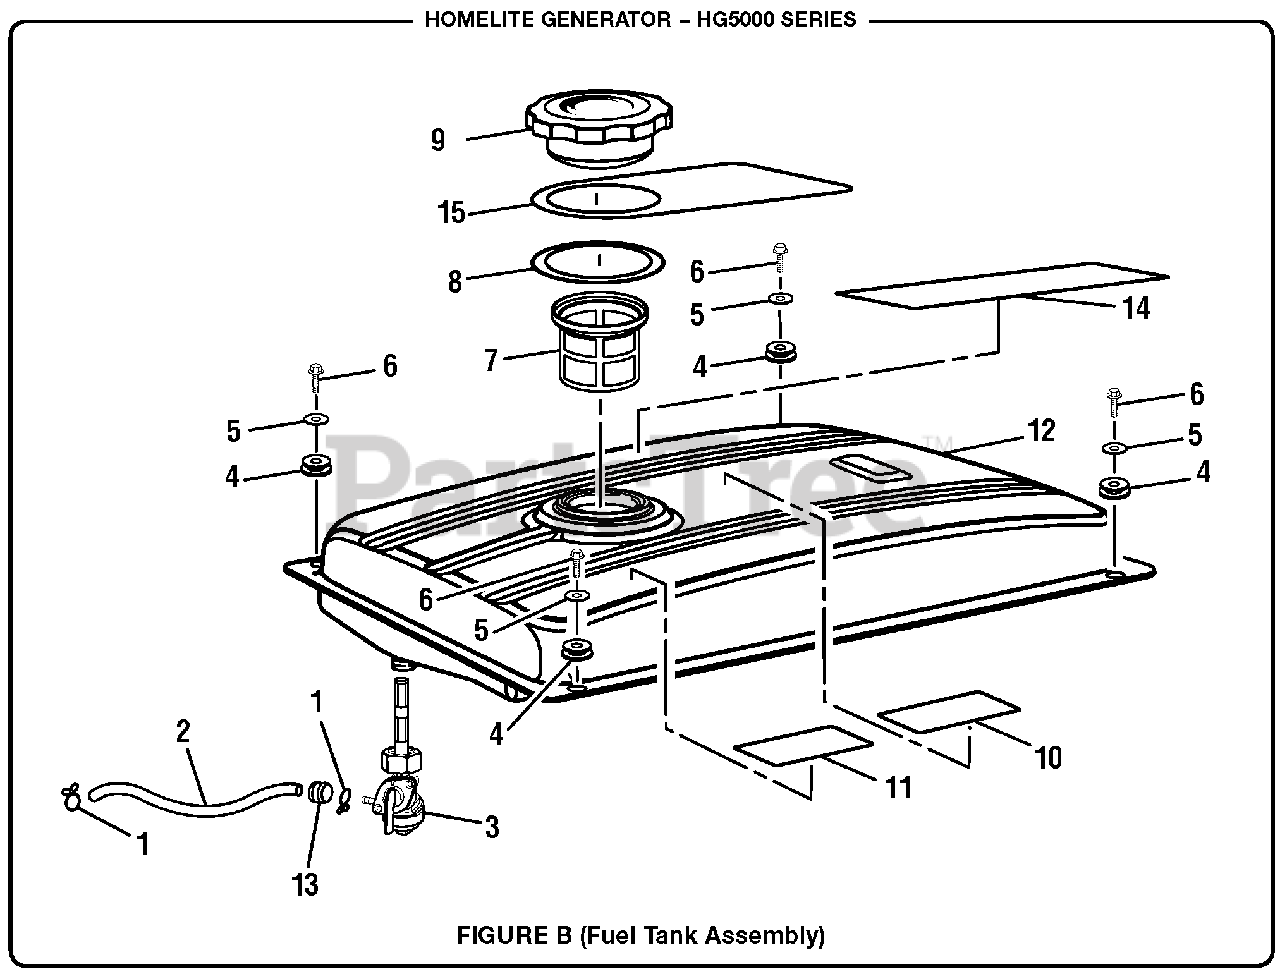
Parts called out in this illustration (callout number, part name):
1	Fuel Line Clamp
2	Fuel Line Hose
3	Fuel Valve Assembly
4	Bushing w/Insert
5	Washer (M6)
6	Bolt (M6 x 25 mm, Flange Hd.)
7	Fuel Tank Screen
8	Gasket (Fuel Cap)
9	Fuel Cap Assembly
10	E85 Label
11	CPSC (English) Label
12	Fuel Tank
13	Grommet (Fuel Line)
14	Danger Label
15	Engine Warning Hang Tag
